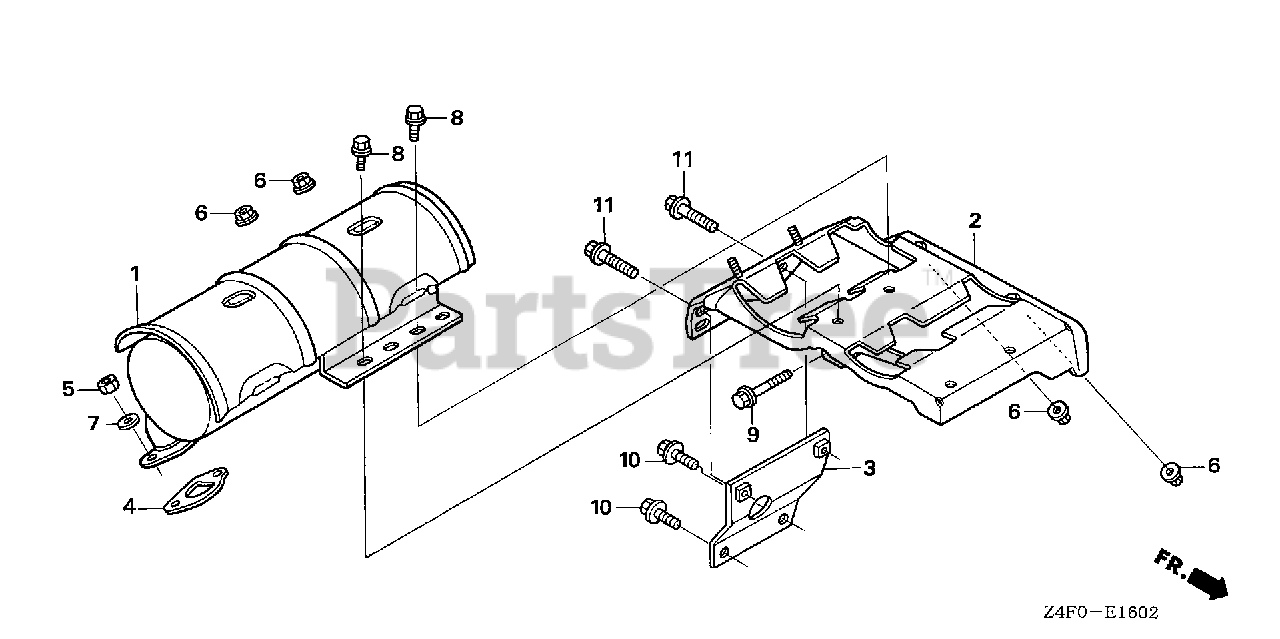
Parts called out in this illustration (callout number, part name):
2	STAY, MUFFLER
3	STAY, MUFFLER
4	GASKET, MUFFLER
5	NUT, HEX. (8MM)
6	NUT, FLANGE (6MM)
8	BOLT, FLANGE (6X16)
9	BOLT, FLANGE (6X25)
10	BOLT, FLANGE (8X12)
11	BOLT, FLANGE (8X18)
